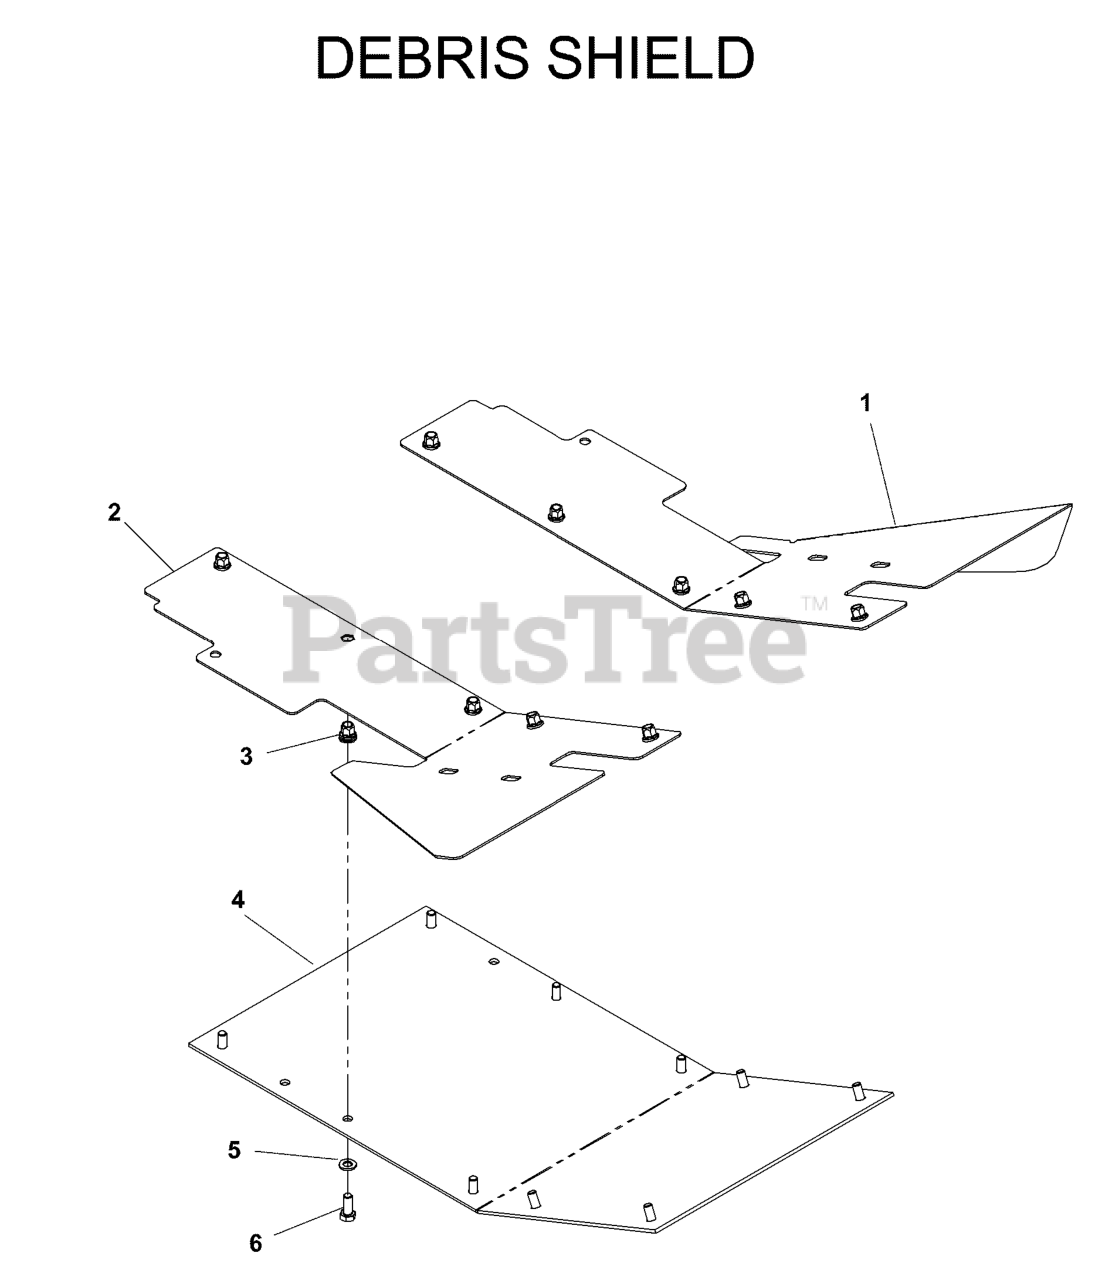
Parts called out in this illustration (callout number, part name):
2	DECAL, BZ34
5	WASHER - 15X7.3X1.6
6	SCREW 8X20
